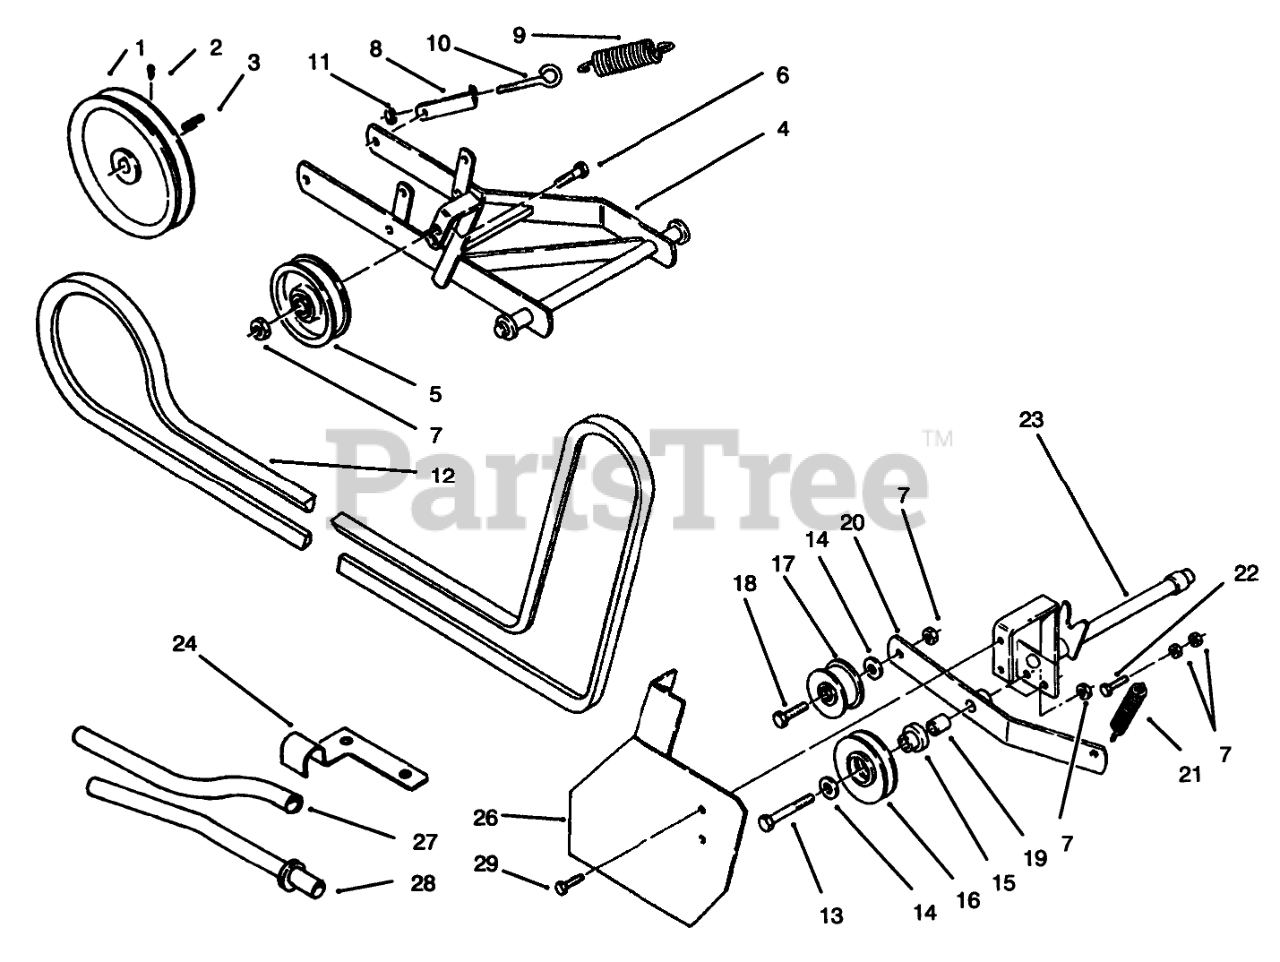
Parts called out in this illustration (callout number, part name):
1	PULLEY
2	KEY-STRAIGHT
3	SCREW-SQH
4	HITCH ASM RED
5	PULLEY-IDLER
6	HEX HD CAP SCREW
7	NUT-HEX
8	BRACKET - SPRING RED
9	SPRING
10	EYEBOLT
11	NUT-LOCK, NI
12	V-BELT
13	SCREW-HH
14	WASHER-FLAT
15	SPACER
16	PULLEY-IDLER
17	IDLER PULLEY
18	SCREW-HH
19	SPACER
20	ASSY IDLER ARM R
21	SPRING-BRAKE
22	SCREW-HH
23	ASSY SUPPORT R
24	CLAMP-CONDUIT R
26	ASM: FRONT IDLER R
27	TUBE-CONDUIT R
28	TUBE ASSY COMPLET R
29	Bolt
